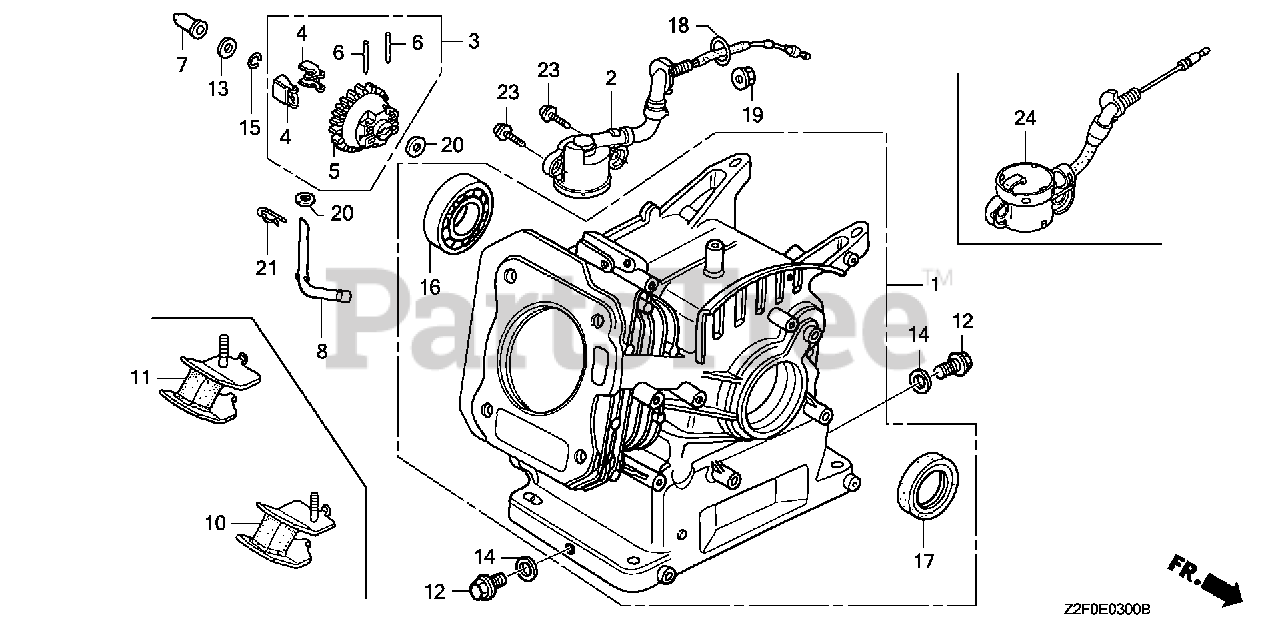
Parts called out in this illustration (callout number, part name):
1	CYLINDER ASSY. (OIL ALERT)
2	SWITCH ASSY., OIL LEVEL
3	GOVERNOR ASSY.
4	WEIGHT, GOVERNOR
5	HOLDER, GOVERNOR WEIGHT
6	PIN, GOVERNOR WEIGHT
7	SLIDER, GOVERNOR
8	SHAFT, GOVERNOR ARM
12	BOLT, DRAIN PLUG
13	WASHER, THRUST (6MM)
14	WASHER, DRAIN PLUG (10.2MM)
15	CLIP, GOVERNOR HOLDER
16	BEARING, RADIAL BALL (6205TMB) (NTN)
17	OIL SEAL (25X41X6) (NOK)
18	O-RING (13.5X1.5) (ARAI)
18	O-RING (14MM) (NOK)
19	NUT, FLANGE (10MM)
20	WASHER, PLAIN (6MM)
21	PIN, LOCK (8MM)
23	BOLT, FLANGE (6X12)
